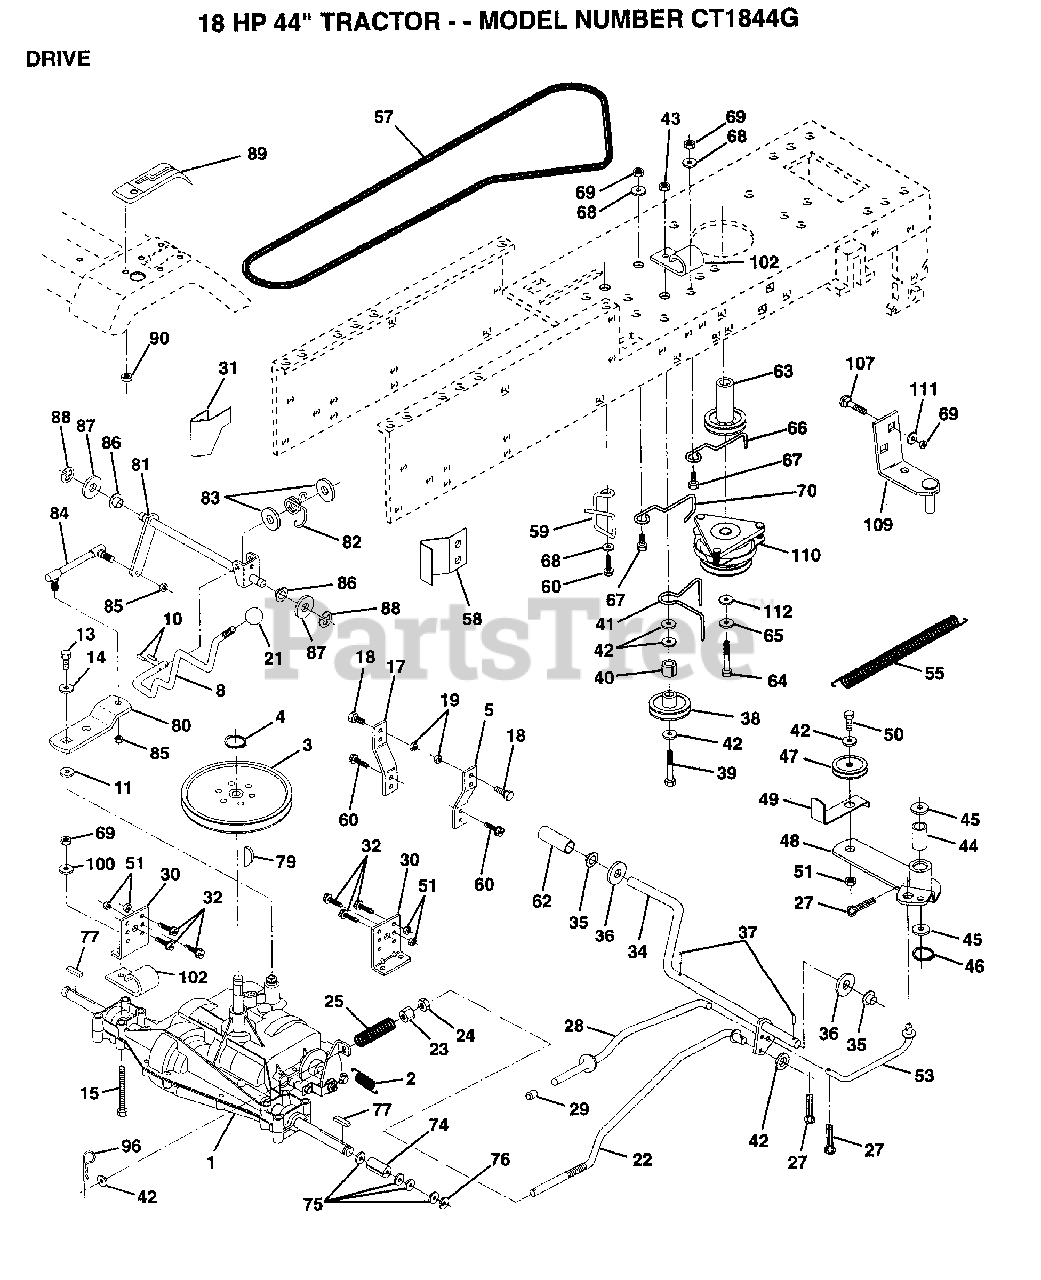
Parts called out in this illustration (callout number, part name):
1	TRANSAX. PRLES.
3	PULLEY TRANSAXLE
4	RING
5	BRKT TRANS RH
10	PIN COTTER 1/8
11	WASH-SHFT PLT LT
14	WASHER PM
15	BOLT HEX
17	BRKT TRANS LH
18	SCREW
21	CONTROL KNOB LT
22	ROD BRAKE
23	NUT
24	NUT
25	"SPRING,ROD BRAKE"
27	COTTER PIN
28	BRAKE PARK ROD
30	STRAP TORQUE
31	KEEPER BELT LH
35	NYLON BEARING
36	WASHER LT
38	PULLEY.IDLER.FLAT
39	BOLT
40	SPACER T
41	BELT KEEPER LT
42	WASHER
44	"LY, BEARING"
45	WASHER LT
46	KLIP RING
48	ARM IDLER
49	RETAIN BELT
53	"LINK, CLUTCH T"
55	"SPRING, RETURN LT"
57	BELT.GRDRV.94.75
58	"KEEPER,BELT RH"
59	KEEPER BELT CNTSP
60	SCREW
62	PEDAL COVER T
63	PULLEY ENGINE
66	KEEPER BELT ENGLH
67	BOLT
68	WASHER
69	NUT
70	"KEEPER,BLT ENG LT"
74	SPACER HYT
75	WASHER
76	E RING HYT
77	SQ KEY STD
80	"ARM,SHIFT"
81	"SHAFT,SHIFTER"
82	"SPRING,TORSION"
83	WASHER
84	"ROD,TIE "
85	NUT 1/4-28
86	BUSHING
87	WASHER D
88	KLIP RING
89	CONSOLE SHIFTER
90	NUT
96	RETAINER M
100	WASHER M
102	CLIP T
107	BOLT
109	BRACKET.ASM.MTG
111	WASHER T
112	WASHER
